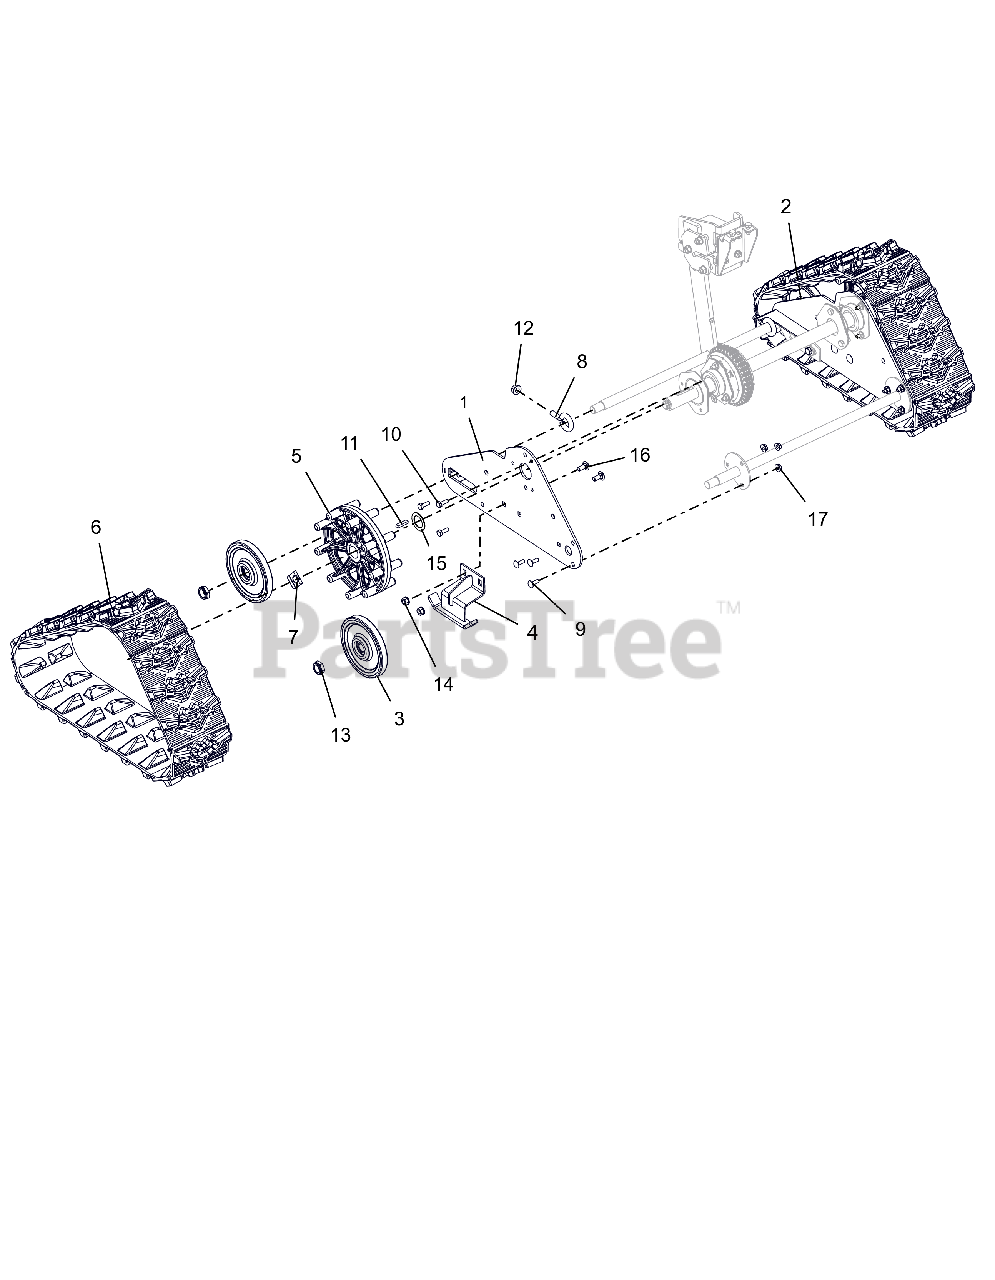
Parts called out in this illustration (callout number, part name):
1	SIDE PLATE, RH-TRACK
2	SIDE PLATE, LH-TRACK
3	WHEEL, BOGIE - SINGLE BEARING
4	RUNNER, GUIDE-TRACK
5	WHEEL, MACHINED DRIVE
6	TRACK, RUBBER
7	CLIP, SNAP .625 DIA
8	BLT-EYE .375-16X.880 YWZC
9	BLT, RHSN .25-20X.750 G5 ZCC
10	BLT, HEX .25-20X.75 G5 ZCC
11	KEY-RECT .25X.188X1.00
12	NUT-LK-CTR-FLG .375-16 GF ZCC
13	@NUT-LK-NYL .625-18 YWZC
14	NUT-LK-TOP-FLG .312-18 GF ZCC
15	WSHR-FL-STL 1.010X1.505X.062YZ
16	BLT,RHSN .31-18X.75 G5 ZCC
17	NUT-LK-TOP-FLG .250-20 GF ZCC
